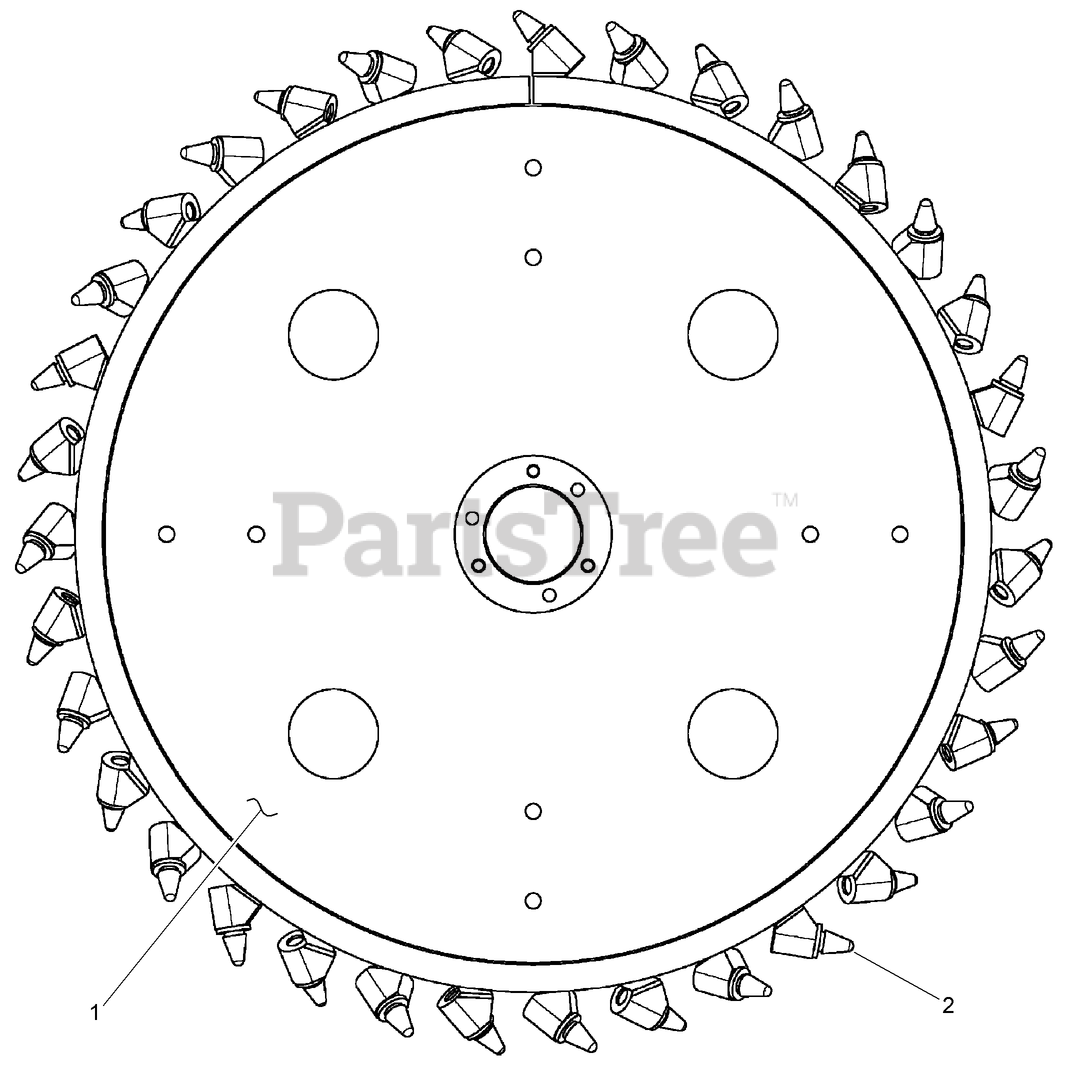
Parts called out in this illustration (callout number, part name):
1	WELDMENT - Cutting Wheel, 3in Wide
1	WELDMENT - Cutting Wheel, 4in Wide
1	WELDMENT - Cutting Wheel, 6in Wide
2	TOOTH - 0.76in Shank
